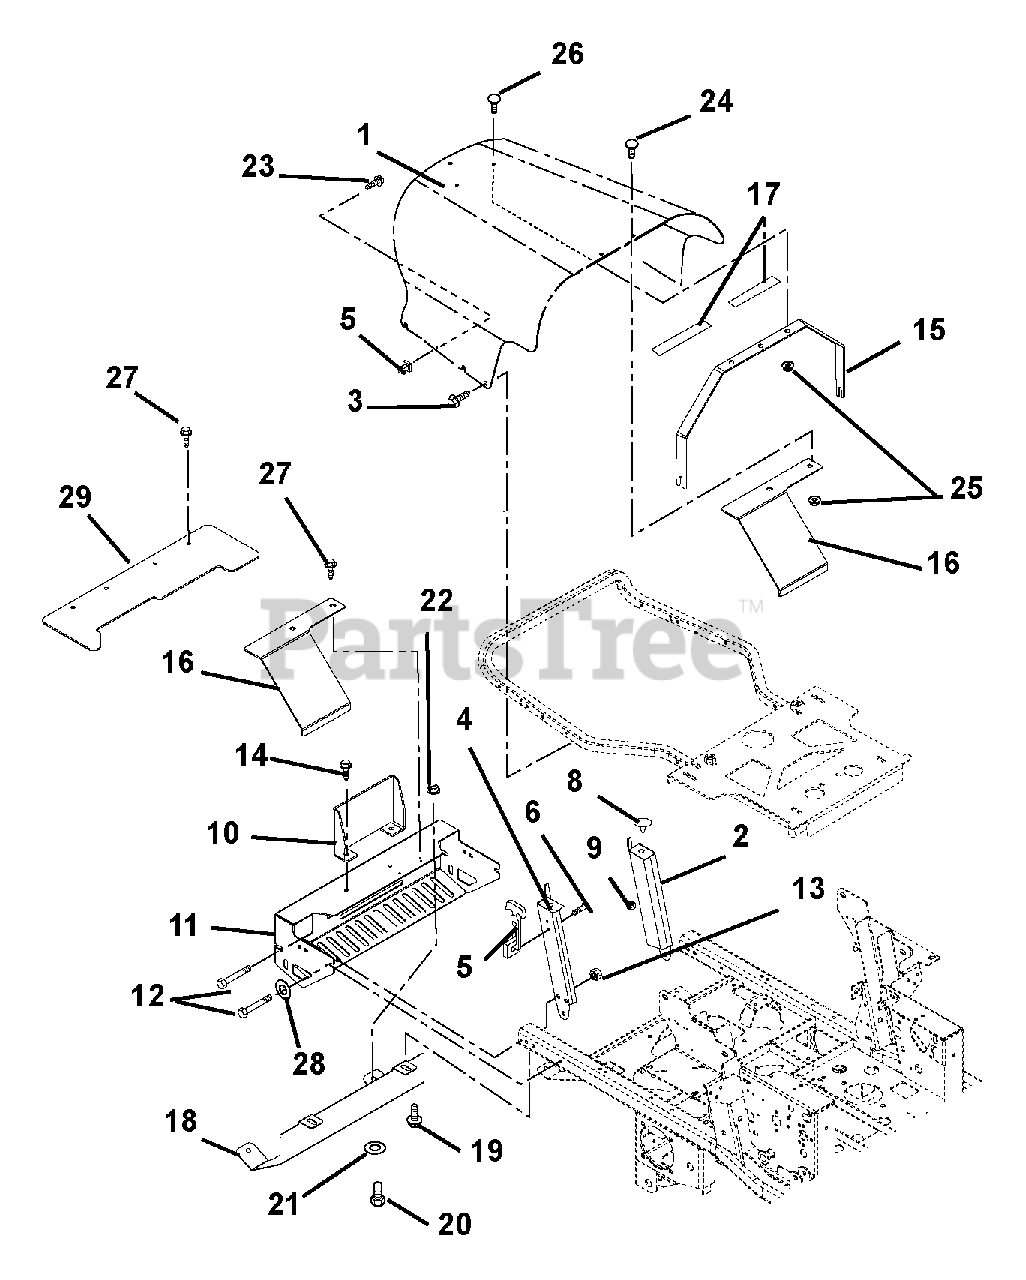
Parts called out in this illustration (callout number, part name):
2	Weldment, Hood Support, Left Hand
3	Screw, Tapping .38-16 x .50 Hex Washer Head
4	Weldment, Hood Support Right Hand
5	Latch, Rubber
6	Screw, Machine 10-24 x .50 Hex Washer Head
7	Screw, Machine 10-24 x 1.50 Hex Washer Head
8	Button Bumper
9	Nut-Spin Lock-Flange .312-18
10	Guard, Muffler
11	Bumper, Rear
12	Bolt, Hex .38-16 x 2.75 Grade 5
13	Nut-Locking-Top-Flange .38-16
14	Screw, Tapping .38-16 x .75 Hex Washer Head
15	Hood Support
16	Guard
17	VHB Tape 4941F
18	Heat Shield
19	Screw-Tapping .38-16 x .50 Hex Washer Head Thread Rolling YWZ
20	Bolt-Hex .38-16 x .75 Grade 5
21	Washer-Flat-Steel .438 x 1.00X.083 YWZ
22	Nut-Locking-Top-Flange .38-16
23	Screw-Machine 10-24 x 1.50 Hex Washer Head
24	Bolt, Round Head Square Neck .25-20 x .50 Grade 5
25	Nut, Locking Top Flange .25-20
26	Bolt, Round Head Square Neck .25-20 x .75 Grade 5
27	Screw, Tapping .25-20 x .50 Hex Washer Head Thread
28	Washer, Flat Steel .406 x .812 x .065
29	Shield, Heat
